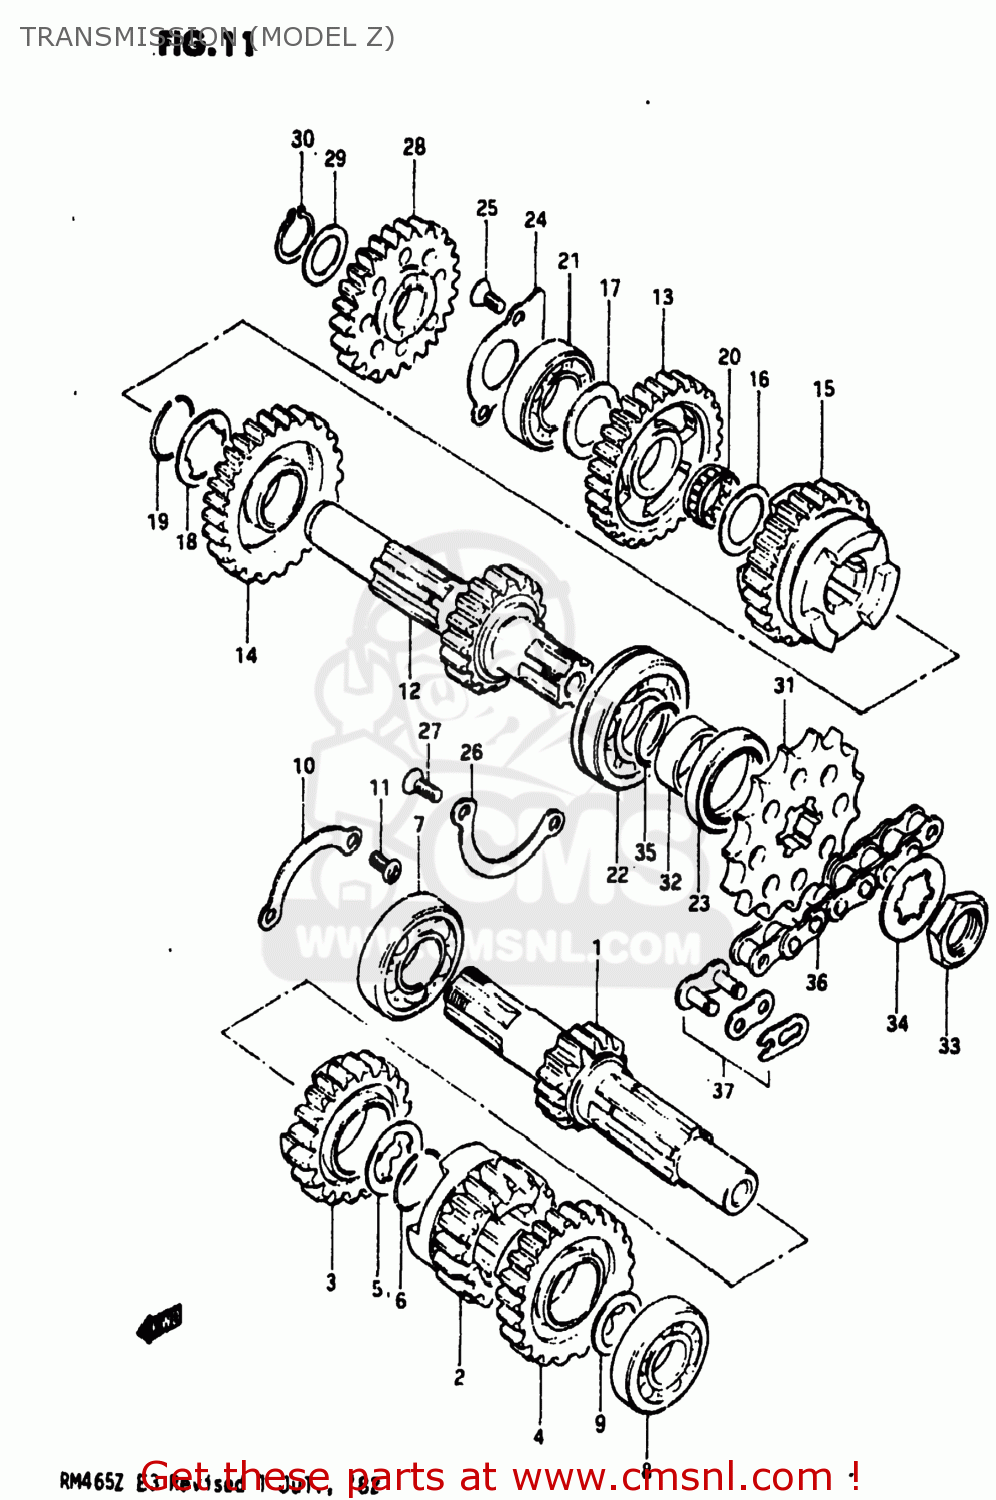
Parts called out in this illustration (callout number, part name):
1	SHAFT,COUNTER
2	GEAR,SECOND DRIVE
3	GEAR,THIRD DRIVE
4	GEAR,FOURTH DRIVE
5	WASHER
6	RING,SNAP
7	BEARING
8	BEARING, LH
9	WASHER
10	RETAINER,BEARING
11	SCREW 6X12
12	SHAFT,DRIVE
13	GEAR,FIRST DRIVEN
14	GEAR,SECOND DRIVEN
15	GEAR,THIRD DRIVEN
16	WASHER
17	WASHER
18	WASHER
19	CIRCLIP
20	BEARING(20X24X10).8
21	BEARING
22	BEARING(28X58X16)
23	SEAL,OIL(35X45X6)
24	RETAINER,DRIVESHAFT
25	SCREW
26	PLATE,DRIVESHAFT BEARING
27	SCREW
28	GEAR,KICK STARTER IDLE
29	WASHER,THRUST
30	CIRCLIP
31	SPROCKET,ENGINE(NT:13)
32	SPACER(28X35X11.4)
33	NUT
34	WASHER,LOCK
35	O RING(D:1.5,ID:27.7)
36	CHAIN ASSEMBLY,DRIVE
37	JOINT ASSEMBLY,CHAIN
